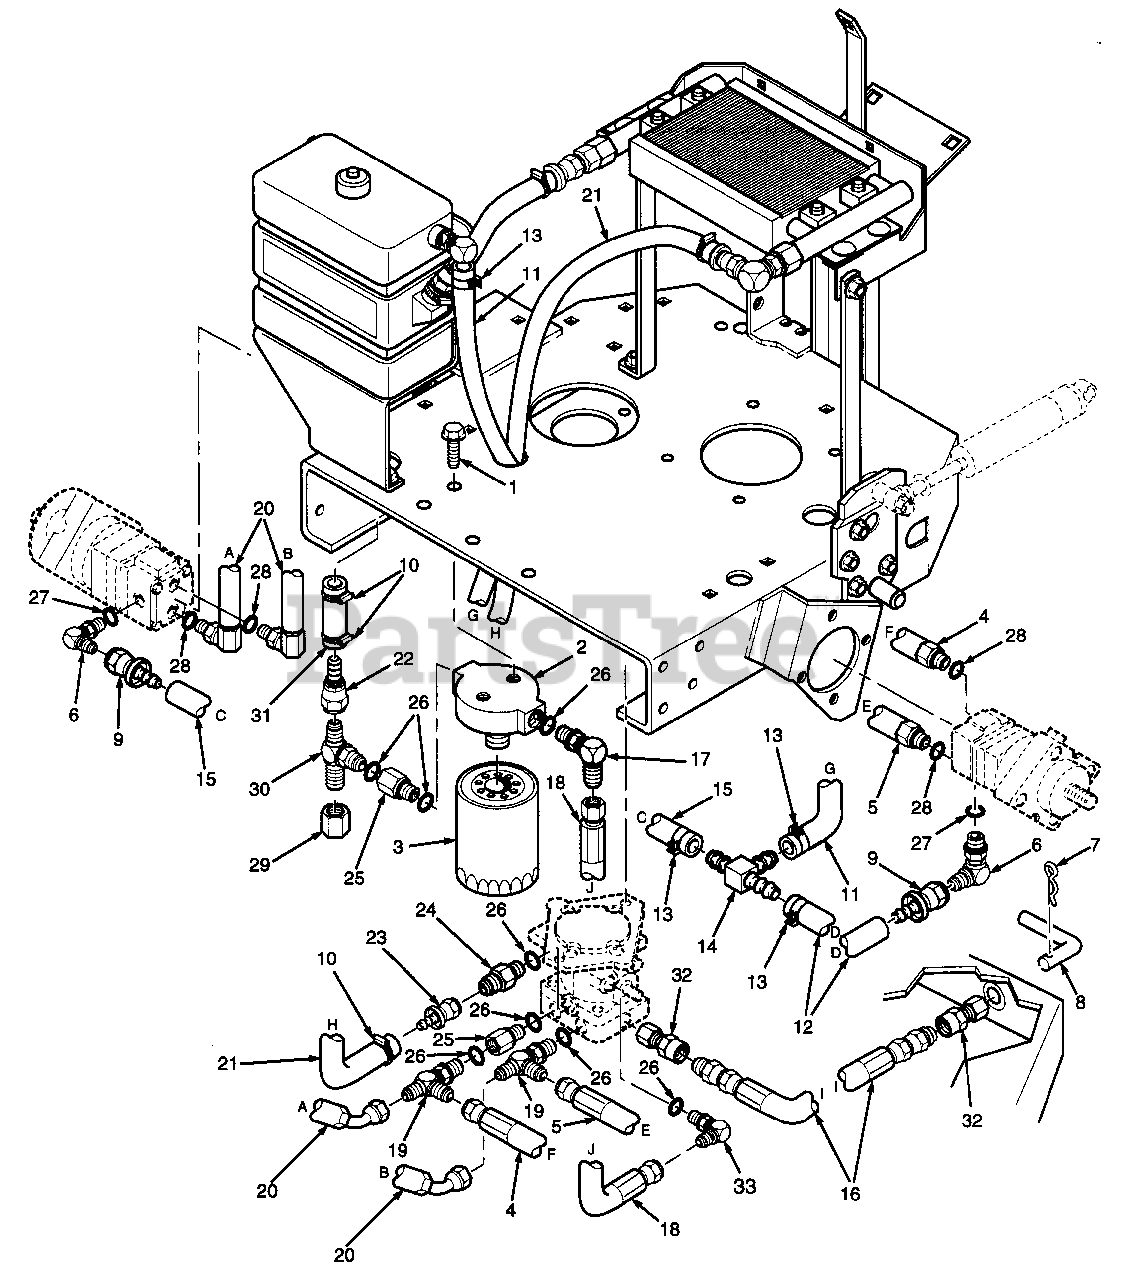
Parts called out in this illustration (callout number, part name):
1	CAPSCREW, 1/4-20 X 1/2 SERR. FL. HEX HEAD
2	FILTER HEAD
3	FILTER, SPIN-ON LUBE
4	HOSE ASSEMBLY
5	HOSE ASSEMBLY
6	ELBOW, 90 DEGREES
7	HAIRPIN COTTER
8	LEVER, DUMP VALVE
9	CONNECTOR, FLARE SWIVEL WITH HOSE BARB
10	HOSE CLAMP
11	HOSE, 1/4 PUSHLOCK X 27.0"
12	HOSE, 1/4 PUSHLOCK X 12.0"
13	HOSE CLAMP
14	TEE UNION, PUSHLOCK HOSE
15	HOSE, 1/4 PUSHLOCK X 12.0"
16	HOSE, DUMP VALVE
17	ELBOW, 90 DEG.
18	INLET HOSE, 3/4" ID
19	TEE, 1/2" RUN
20	MOTOR HOSE
21	HOSE, PUMP TO OIL COOLER
22	COUPLING, FLARE SWIVEL
23	COUPLING, FLARE SWIVEL WITH BARB
24	TUBE UNION
25	O-RING BUSHING
26	O-RING
27	O-RING
28	O-RING
30	TEE, JIC TO O-RING
31	HOSE, 4.0"
32	COMPRESSION FITTING
33	ELBOW, 90 DEG.
